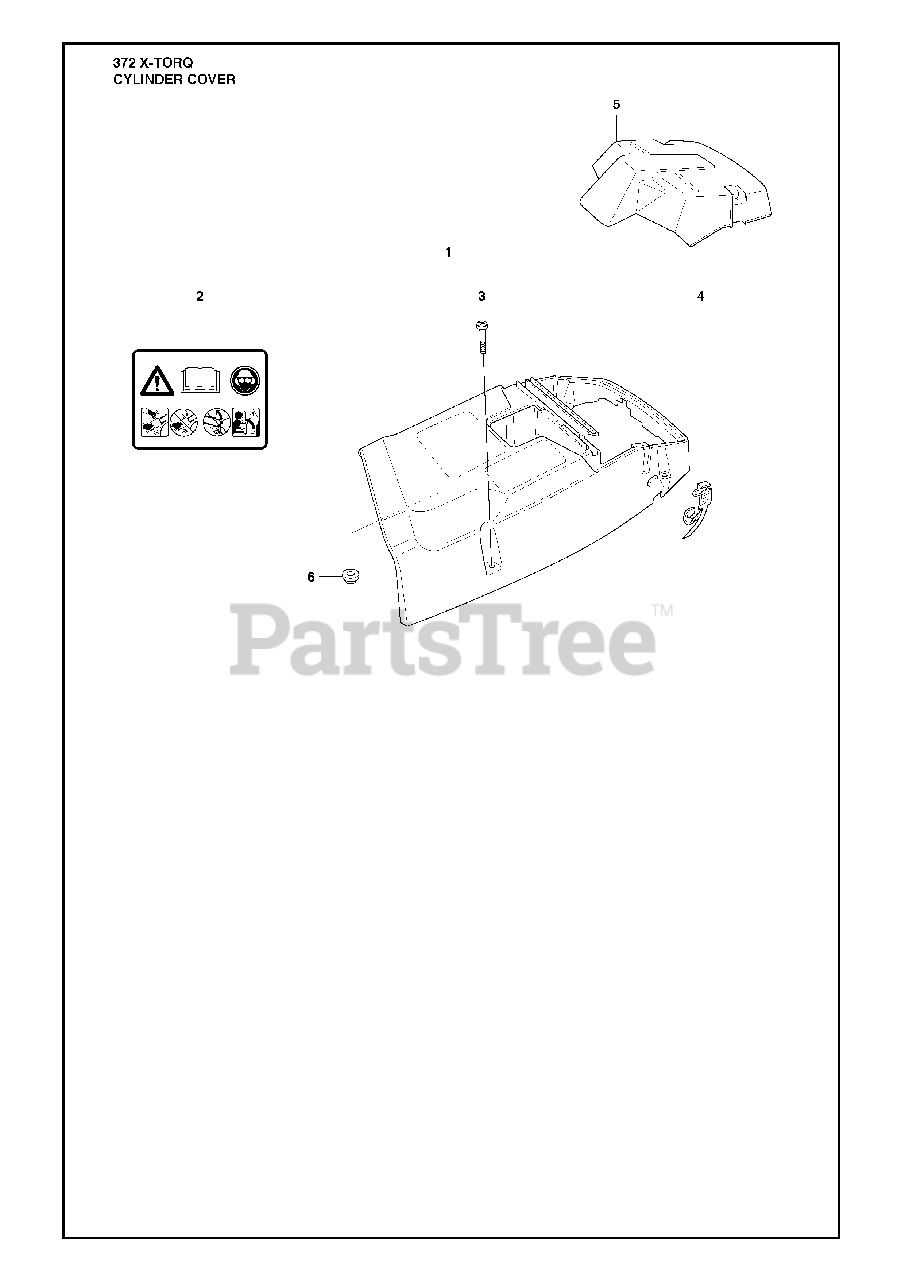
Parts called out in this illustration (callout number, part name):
1	RP CYLINDER COVER ASSY
3	SCREW
5	COVER
